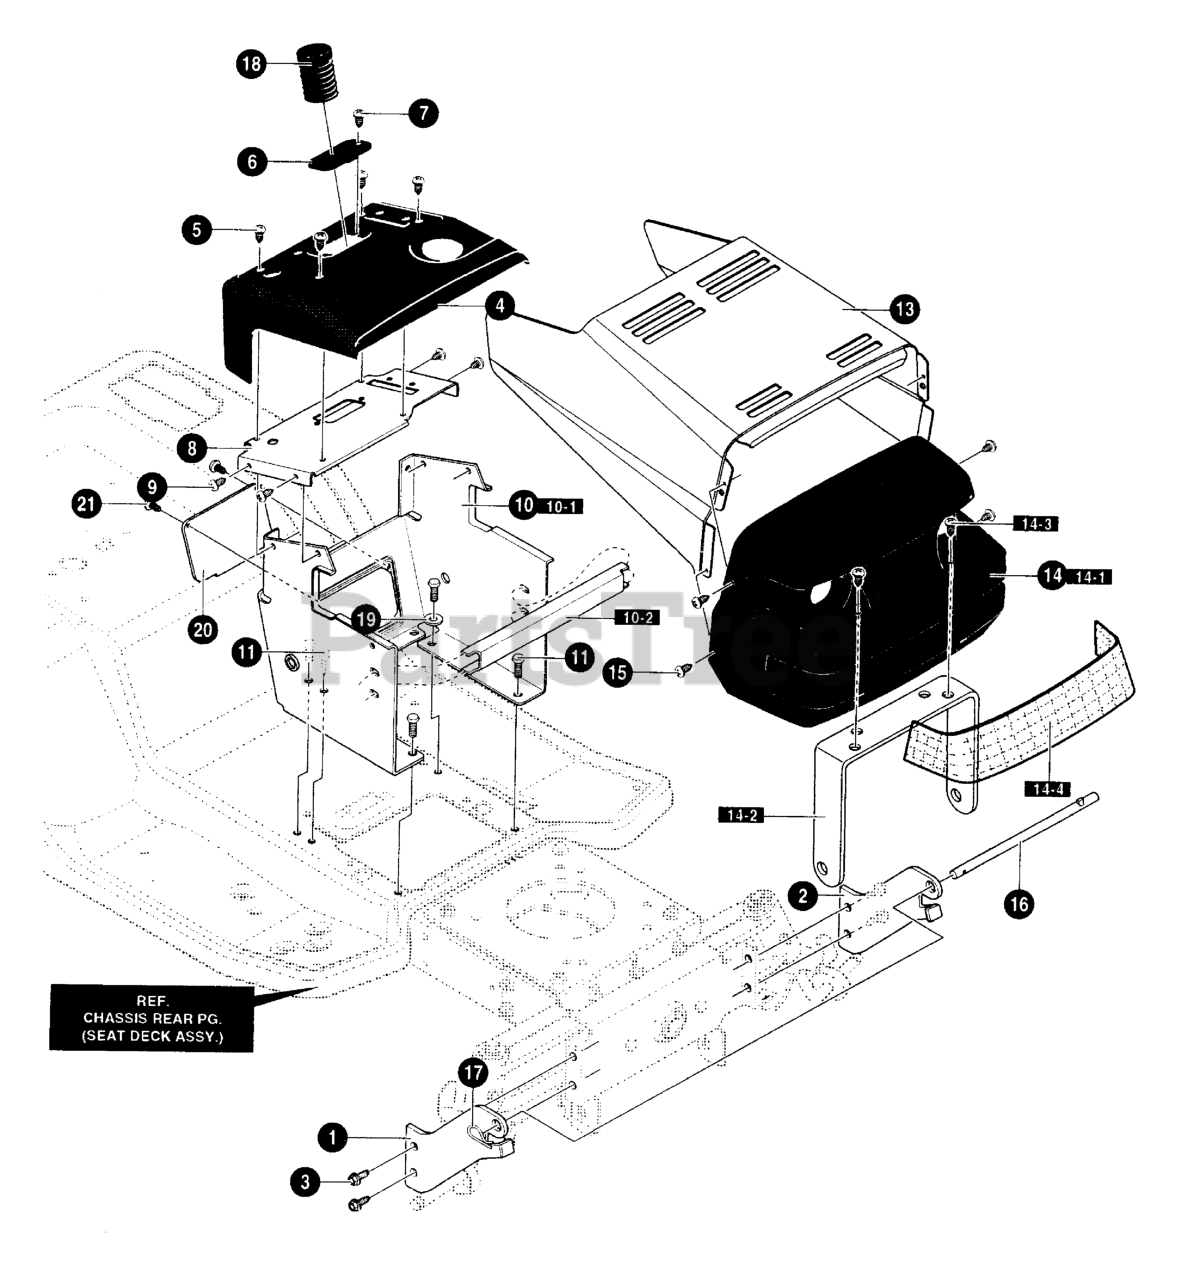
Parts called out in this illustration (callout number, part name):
1	SUPPORT BRACKET RH
2	SUPPORT BRACKET LH
3	SCREW, 5/16-18 x 0.75
5	SCREW, 10-24X.50
6	BEARING
7	SCREW, 1/4-14X.50
8	PLATE, DASH PANEL
9	SCREW, 10-24 X.50
10	LOWER CONSOLE
10-1	SUPPORT, DASH
10-2	SUPPORT, CHANNEL
11	SCREW, 5/16-18 x 0.75
14	GRILLE ASSY.
14-1	GRILLE
14-3	SCREW, 1/4-14 X.75
15	SCREW, PAN TAP
16	ROD, HOOD PIVOT
17	HAIR PIN
18	BELLOW
19	WASHER, BELLVILLE
20	ACCESS PANEL
21	SCREW, 10-24 X.50
